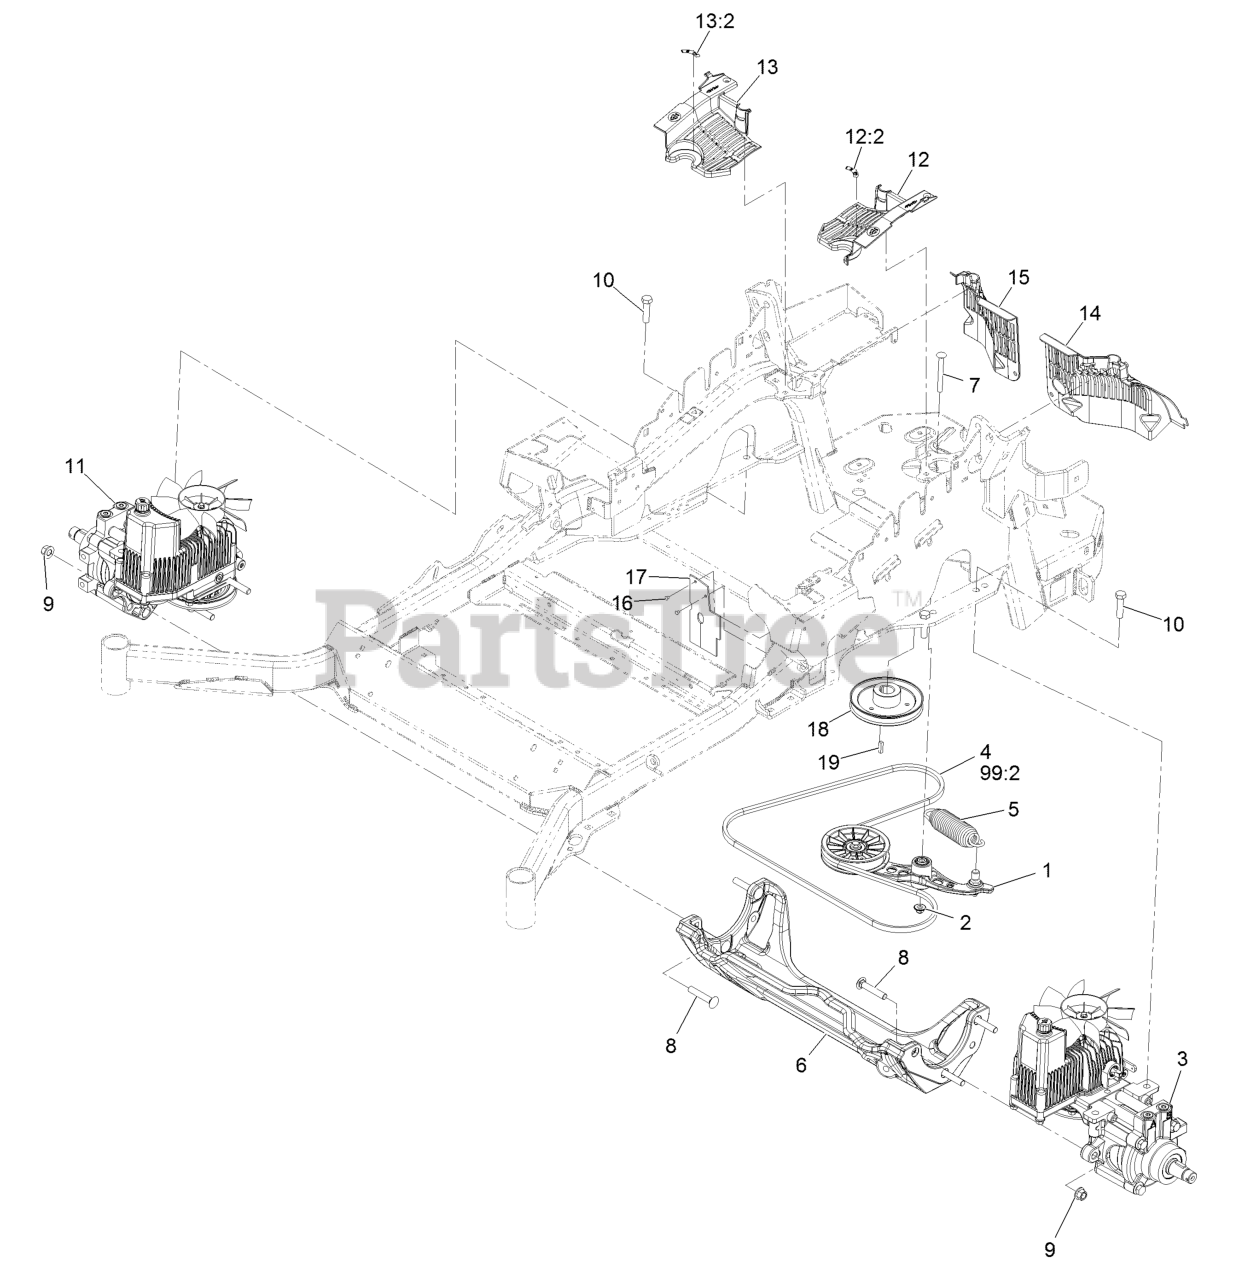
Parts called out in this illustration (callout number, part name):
1	PUMP IDLER ASM
2	Nut-Nyloc 3/8-16 Flg
3	LH HYDRO ASM (16CC W/ SHO
4	BELT
5	SPRING-EXTENSION
6	CRADLE-HYDRO
7	BOLT-SHOULDER, CARRIAGE 3/8-16 X 3 1/2
8	SCREW-CARR
9	Nut-Lock 1/2-13
10	SCREW-HH
11	RH HYDRO ASM (16CC W/ SHO
12	LH HYDRO GUARD ASM
12:2	DECAL-OIL, HYDRO
13	RH HYDRO GUARD ASM
13:2	DECAL-OIL, HYDRO
14	GUARD-HYDRO, REAR (LH)
15	GUARD-HYDRO, REAR (RH)
16	RIVET-POP
17	DEFLECTOR-AIR FLOW
18	SHEAVE
99:2	BELT
